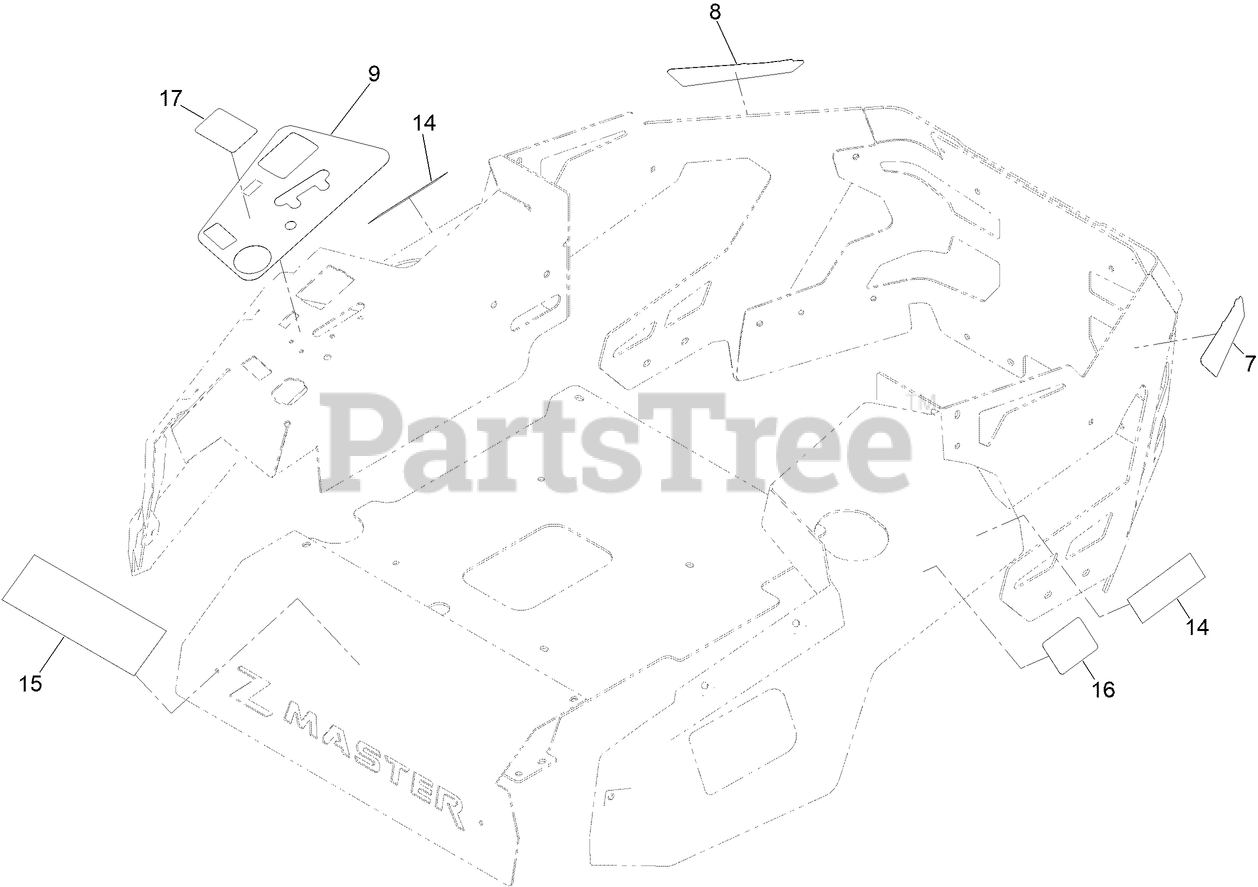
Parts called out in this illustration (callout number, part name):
7	DECAL - HDX PRO
8	DECAL - HDX PRO
9	DECAL-PANEL, CONTROL
14	DECAL- RHHLG2X5
15	DECAL-CPER0002
16	DECAL - CPER001
17	DECAL-CPER0050
